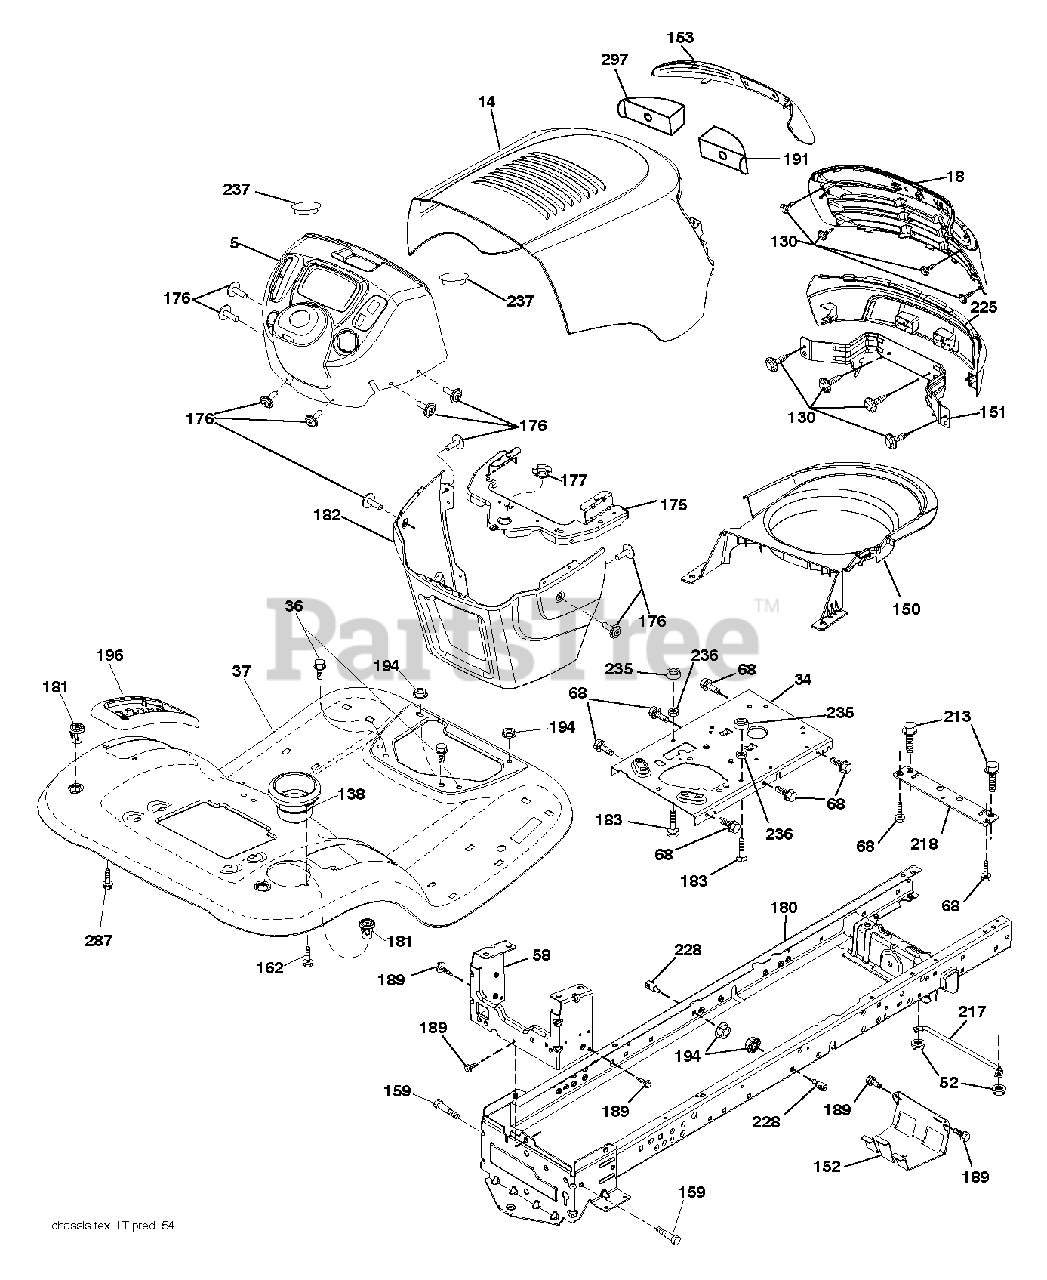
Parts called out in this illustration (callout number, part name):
58	DRAWBAR UPPER
68	SCREW LT
130	SCREW.#10 X 0.750.BOS THREAD
138	CUPHOLDER
152	SHIELD BROWNING
159	SCREW, 3/8-16X3/4
162	SCREW,HEX
176	SCREW.#10-24X5/8.RN.QU
181	FEND/FTRST.PCH.CPH.NFW
183	BOLT.5/16-18X1-1/4 FULL THD
189	SCREW
194	NUT LOCK HEX FLANGE 5/16-18
196	CONSOLE ASM. DECK LIFT
228	STUD.FASTNER.W/D.ANTI-
235	SPACER FENDER
236	JAM LOCK NUT
